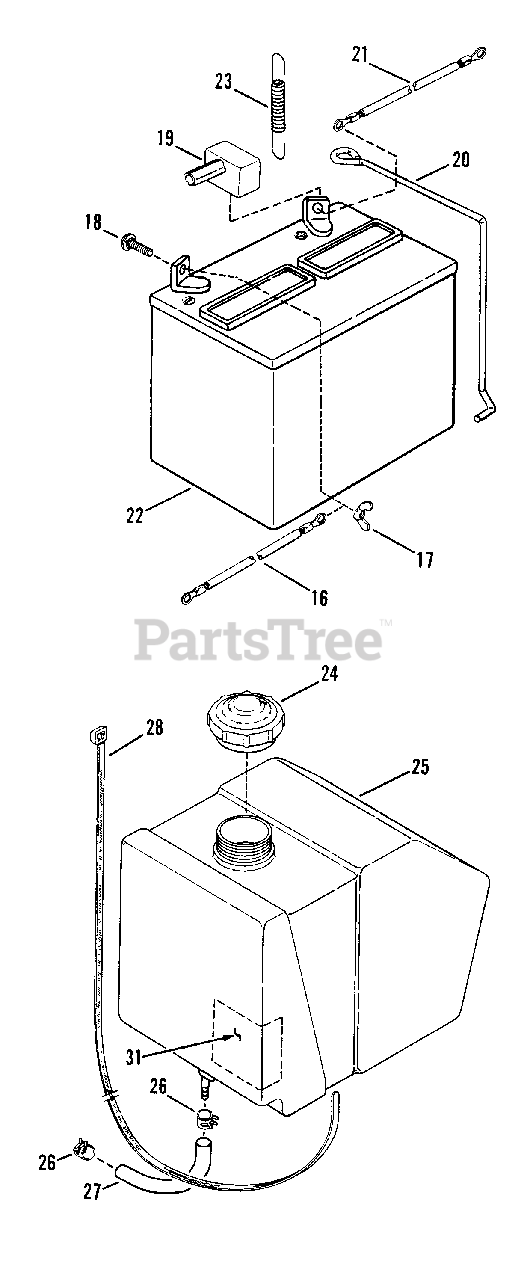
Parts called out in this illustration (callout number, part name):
16	CABLE, Negative Terminal 15" 8 AWG Black
17	WING-NUT, 1/4-20
18	BOLT, 1/4-20 x 3/4" Short Neck Carriage
19	COVER, Positive Terminal
20	CLAMP, Battery
21	CABLE, Positive Terminal 11" 8 AWG Red
22	KIT, Battery, 12 Volt
23	SPRING, Battery Bracket
24	CAP, Fuel Tank
25	TANK, Fuel w/cap
26	CLAMP, Fuel Line .490 x .31
27	LINE, Fuel (14.5" Long) (No longer available)
28	CABLE-TIE, Fuel Tank Hold Down
31	HEAT SHIELD, Fuel Tank 3" x 5.5" (No longer available)
